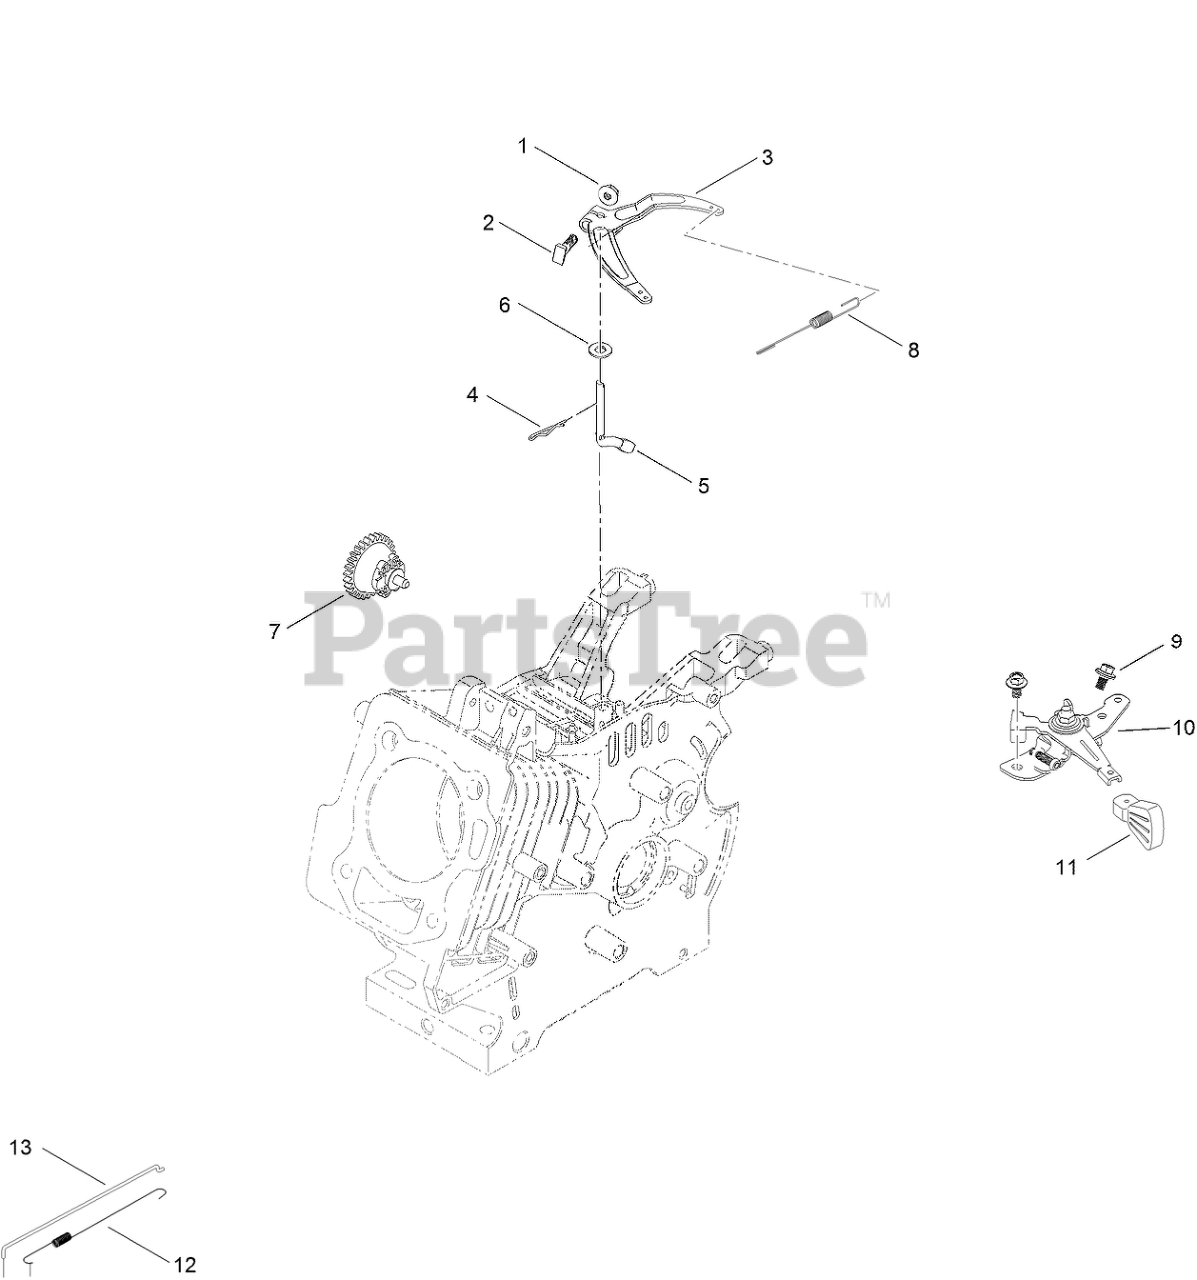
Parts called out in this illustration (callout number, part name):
1	NUT-FLANGE
2	BOLT-ARM, GOVERNOR
3	ARM-GOVERNOR
4	PIN-HAIR
5	SHAFT-GOVERNOR
6	WASHER-PLAIN
7	GOVERNOR GEAR ASM
8	SPRING-GOVERNOR
9	SCREW-HHF
10	THROTTLE CONTROL ASM
11	KNOB-CONTROL, THROTTLE
12	SPRING-RETURN, THROTTLE
13	ROD-GOVERNOR
